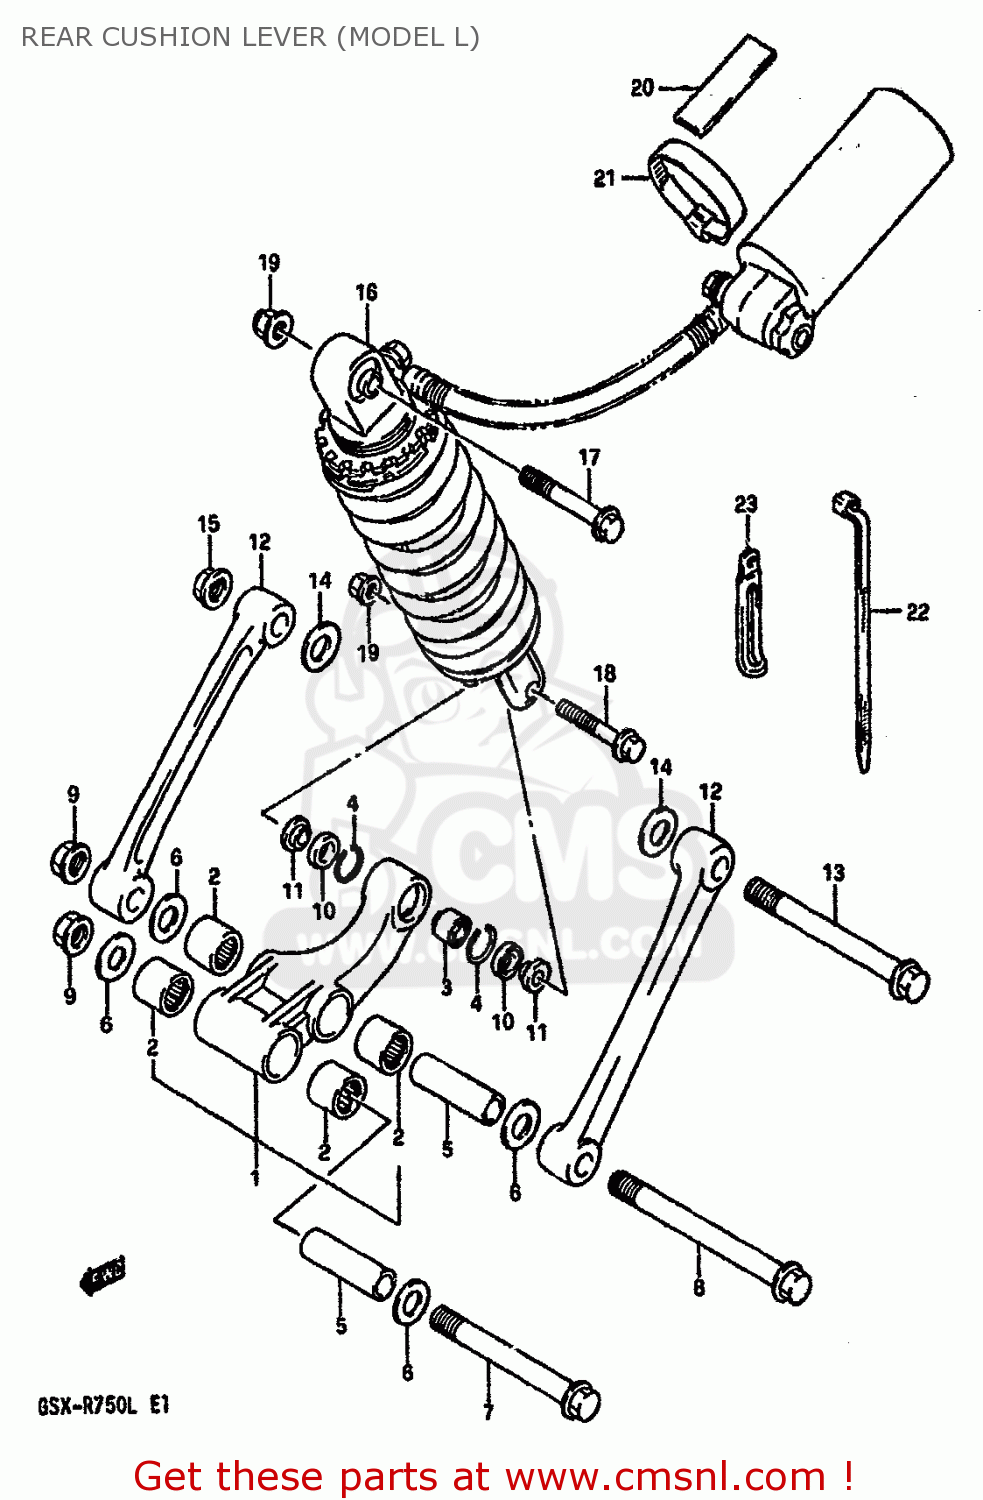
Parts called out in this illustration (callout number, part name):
1	LEVER SET,REAR CUSHION
2	BEARING(20X27X23.5)
3	BEARING,RR CUSHION LEVER
4	RING,STOPPER
5	SPACER,RR CUSHION LEVER
6	WASHER
7	SHAFT,RR CUSHION LEVER FR
8	SHAFT,RR CUSHION ROD
9	NUT
10	DUST SEAL,RR CUSHION LEVER RR
11	SPACER
12	ROD,REAR CUSHION
13	SHAFT,RR CUSHION ROD
14	WASHER
15	NUT
16	ABSORBER ASSEMBLY,REAR SHOCK
17	BOLT
18	BOLT(10X54)
19	NUT
20	CUSHION,RESERVOIR TANK
21	CLAMP
22	CLAMP(L:165)
23	CLAMP
